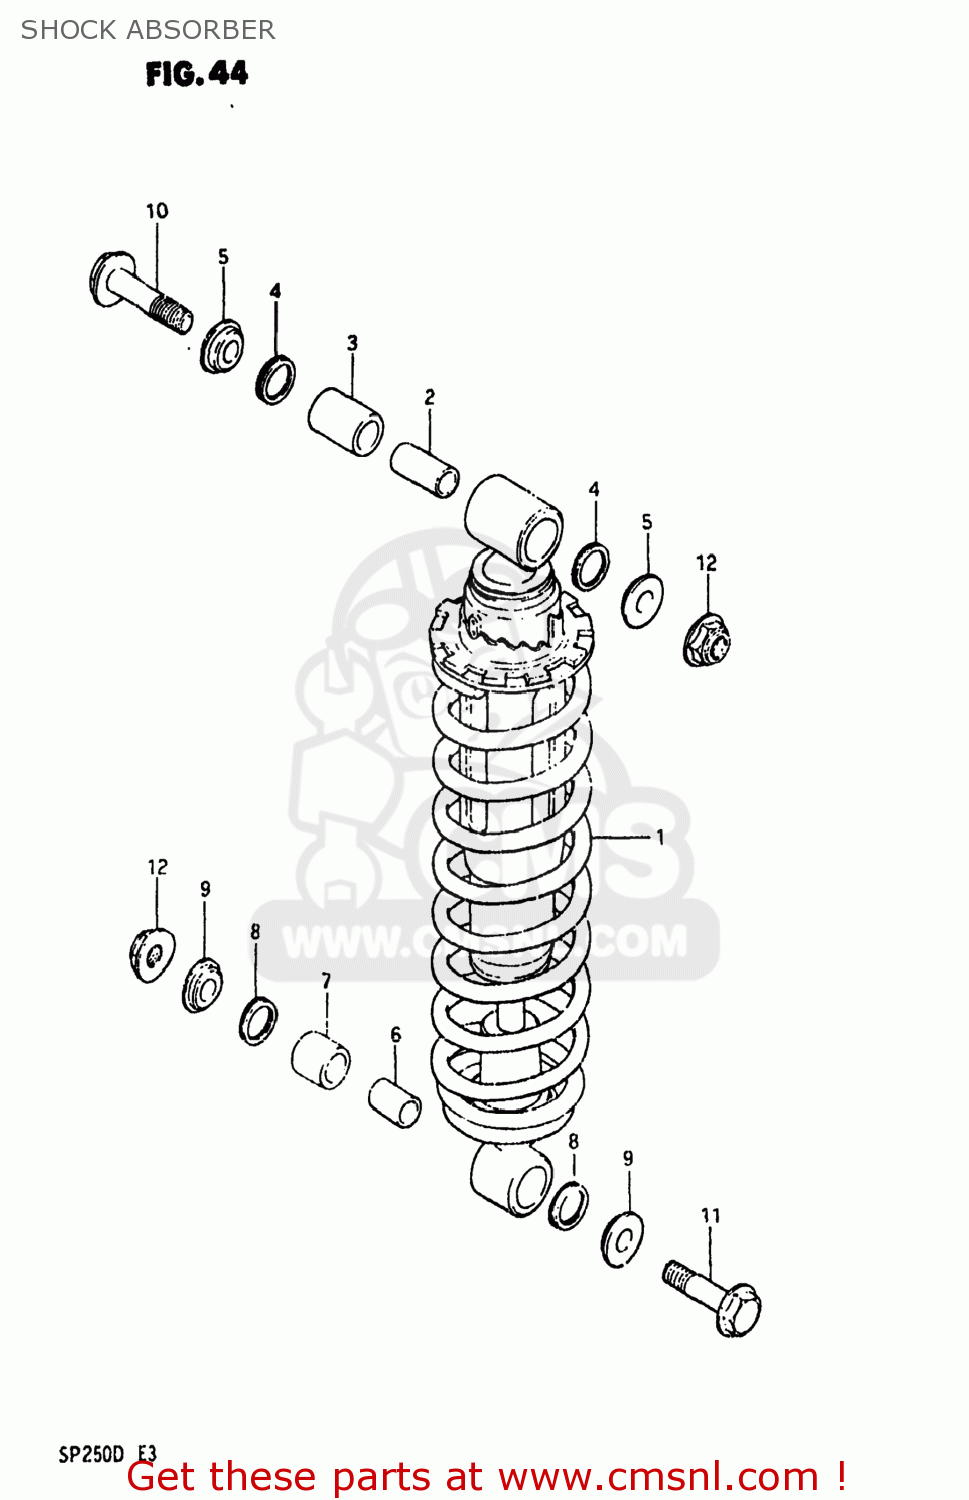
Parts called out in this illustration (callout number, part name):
1	ABSORBER ASSEMBLY,REAR SHOCK
2	BUSH
3	BUSHING,REAR SHOCK,UPPER
4	O-RING,FORK INNER TUBE
5	COLLAR
6	BUSHING,REAR SHOCK ABSORBER
7	BUSHING,REAR SHOCK,LOWER
8	O-RING,FORK INNER TUBE
9	COLLAR
10	BOLT(10X60)
11	BOLT(10X50)
12	NUT
